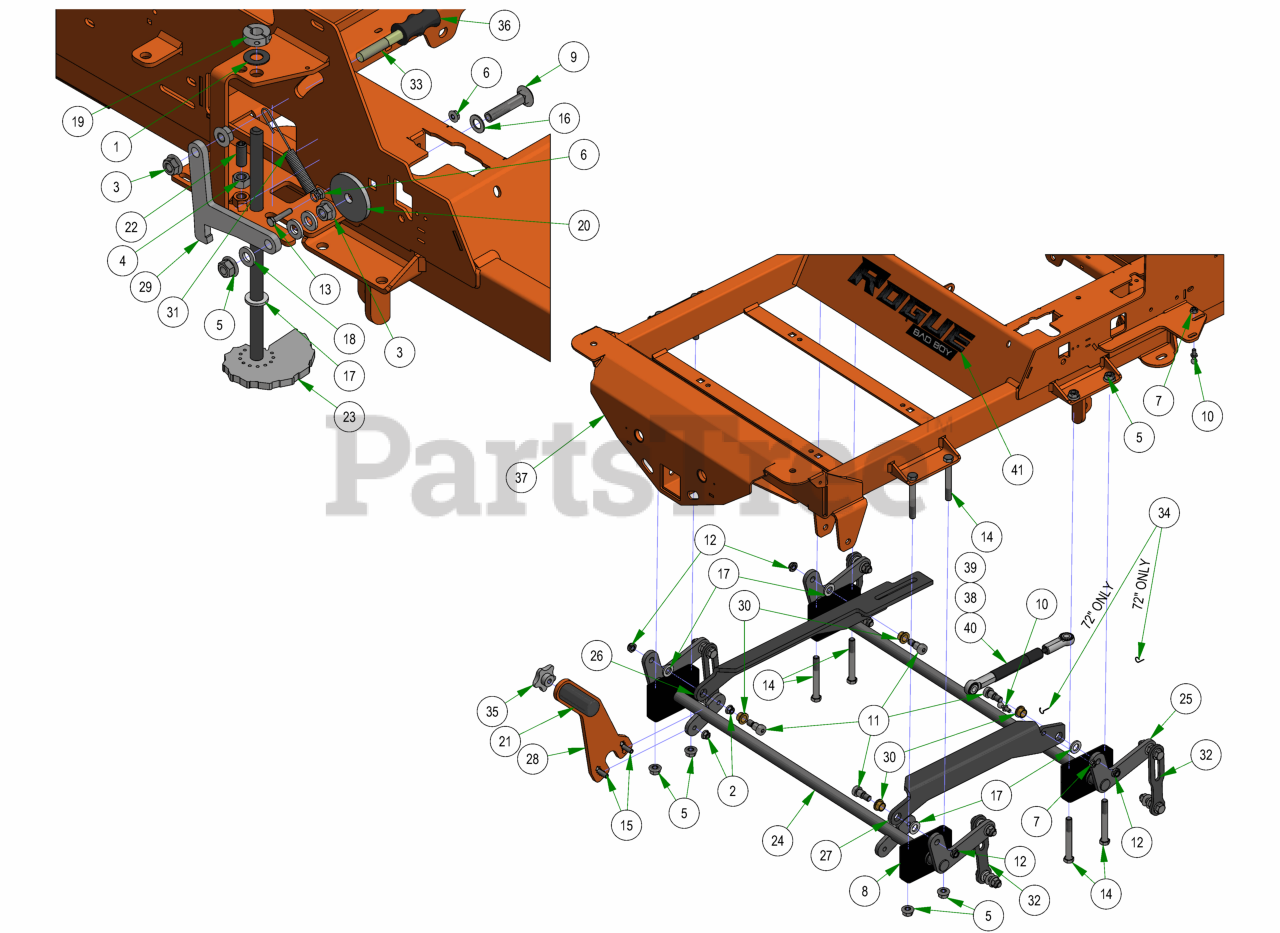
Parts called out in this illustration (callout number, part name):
1	.625 ID x 1.250 OD x .062 THK F W Nylon
2	3 8-16 NYLON INSERT FLANGE LOCKNUT (GR.F) ZINC
3	1 2-13 HEX SERRATED FLANGE NUT HARD ZINC
4	1 2-13 HEX NUT ZINC
5	1 2-13 NYLON INSERT FLANGE LOCKNUT ZINC
6	1 4-20 HEX SERRATED FLANGE NUT HARD ZINC
7	5 16-18 HEX SERRATED FLANGE NUT HARD ZINC
8	Pillow Block Assembly
9	2 1 2 x 1 2 Carriage Bolt
10	13mm Damper Ball Stud-Steering
11	5 8 X 5 8 SOCKET SHOULDER BOLT ZINC YELLOW
12	1 2-13 NYLON INSERT JAM LOCKNUT ZINC
13	1 4-20 X 1-1 4 HEX CAP SCREW (GR.5) ZINC
14	1 2-13 X 4 HEX CAP SCREW (GR.8) ZINC YELLOW
15	3 8-16 X 1-1 4 CARRIAGE BOLT ZINC
16	.517 SQ WDTH ID X .937 OD X .060 THICK F W PHOS OIL
17	.635 ID X 1.120 OD X .140 THICK FLAT WASHER NYLON
18	.505 ID X 1.000 OD X .125 THICK FLAT WASHER NYLON
19	5 8" Split Collar
20	MZ Deck Idler Spacer
21	Knurled Pedal
22	Dial Rod Plunger
23	2019 Outlaw Gen2 Deck Height Dial Rod Assy
24	2019 Outlaw Actuator - Front
25	2019 Outlaw Actuator - Rear
26	2019 Actuator Linkage – Right – Black
27	2019 Actuator Linkage - Left - Black
28	Foot Lift Upright Lever
29	2019 Outlaw Deck Travel Lock
30	.627 ID X .753 OD X .500 LGTH X 1.000 FLG OD X .094 FLG THICK FLANGED BEARING OIL-IMPREG BRNZ
31	Brake Spring
32	Deck Hanger Assembly
33	Seat Bracket Pin
34	Security Ring - PC744
35	Foot Pedal Knob 1 2-13
36	Travel Lock Rubber Grip
37	2023 Rogue Frame - Painted
38	200 lb Gas Spring- 54" Deck outlaw
39	250lb Gas Spring - 61" Deck
40	300lb Gas Spring - 72" Deck
41	Rogue back Plate & Front Decal
